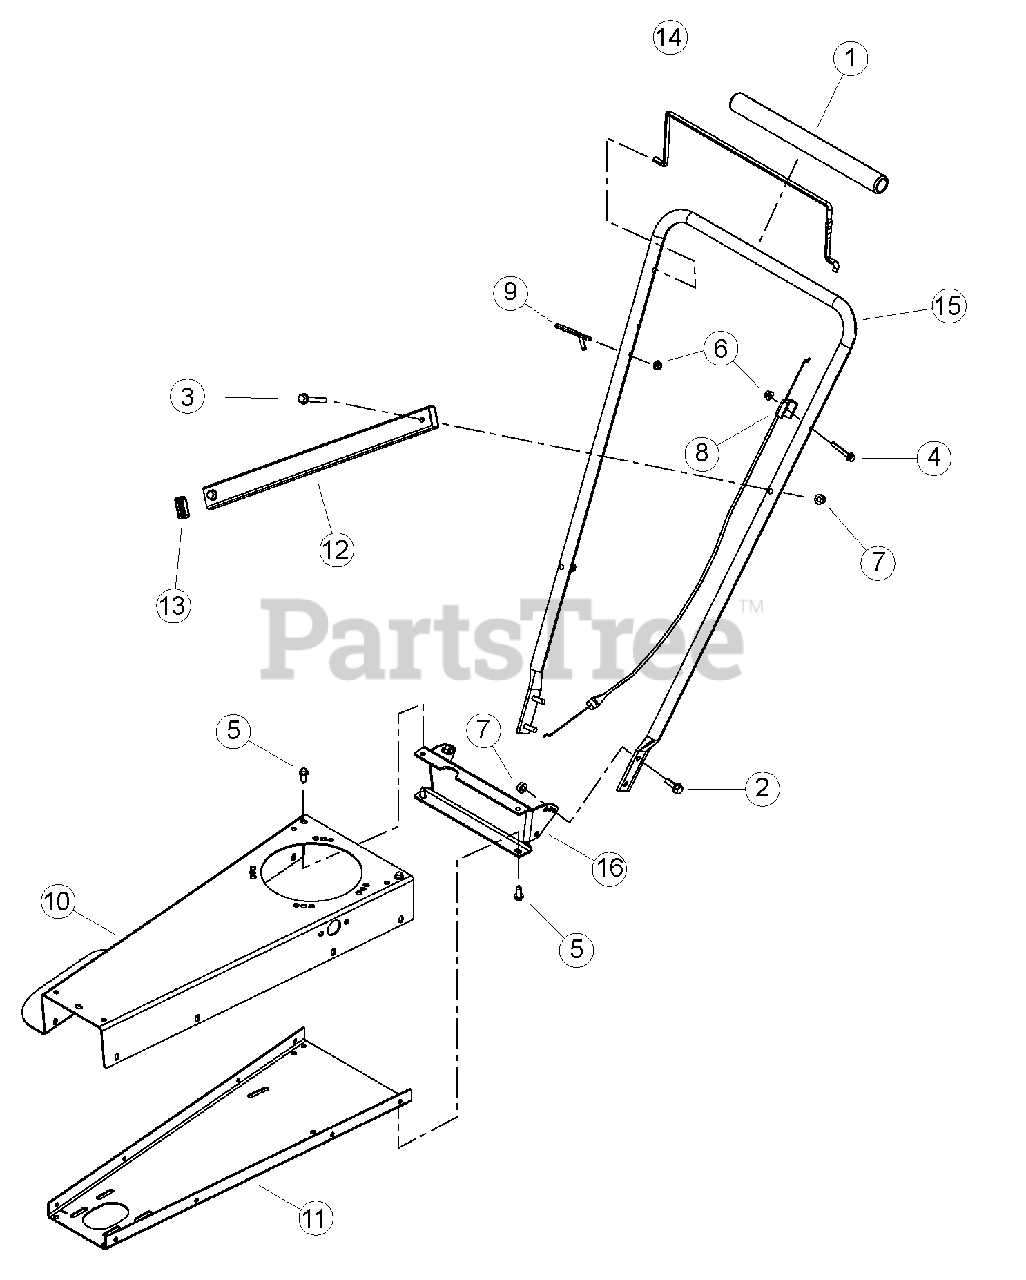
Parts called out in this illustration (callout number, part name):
1	PAD, FOAM HANDLEBAR
2	BOLT, 5/16 X 1 FLANGE NC
3	BOLT, 5/16 X 2-1/4 FLANGE NC
4	BOLT, 1/4 X 1-3/4 FLANGE NC
5	SCREW, 11/32 X 7/8 HWH AB THREAD ZP
6	NUT, 1/4-20 NYLOCK-FLANGE
7	NUT, 5/16-18 NYLOCK-FLANGE
8	CABLE, BRAKE CONTROL SUBARU
9	GUIDE, RECOIL ROPE
10	BODY, TRIMMER STANDOFF
11	BOTTOM, TRIMMER STANDOFF
12	ASSEMBLY, WT LINE HOLDER
13	CAP, PLASTIC 3/4 X 1-1/2 TUBE
14	BAIL, TRIMMER
15	HANDLEBAR, TRIMMER
16	CHANNEL, HANDLE SUPPORT
